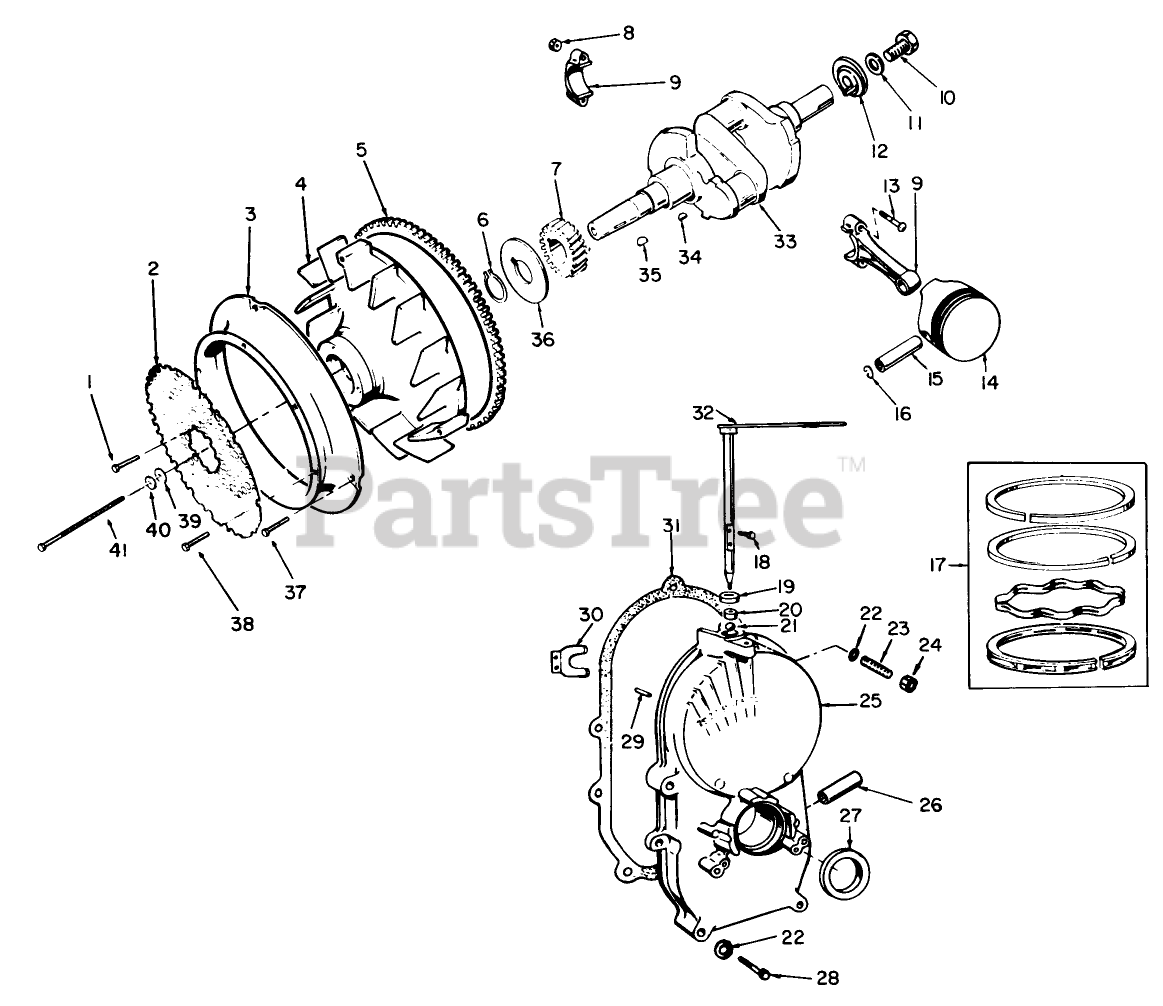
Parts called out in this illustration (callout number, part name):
1	Screw, Cap-Hex Head Locking
2	Guard, Flywheel
3	Venture, Blower Wheel
4	Flywheel (Incl. Ref. #5)
5	Gear, Ring
6	Ring Retaining
7	Gear Crankshaft
8	Nut, Hex-Crown Lock
9	Rod, Connecting-Standard (Incl. Ref. #8 13)
10	Screw, Cap Hex Hd.
11	Washer, Lock-Spring
12	SPACER
13	Bolt, Special-Connecting Rod
14	Piston and Pin-Standard (Incl. Ref. #15 16)
15	Pin, Piston
16	Ring, Retaining
17	Ring Set, Piston-Standard
18	Screw, Machine-Pan Hd.
19	Ball, Bearing-Governor Shaft
20	Bearing, Governor Shaft
21	Seal, Oil-Governor Shaft
22	Washer, Flat Copper
23	Stud, Gear Cover-Top Hole
24	Nut, Gear Cover Top Hole
25	Gear Case Assembly (Incl. Ref. #1 8-21, 23-24, 27-28 30)
26	Tube, Vacuum Port
27	Seal, Oil-Crankshaft
28	Screw Cap Hex Hd.
29	Pin, Dowel-Governor Cup Stop
30	Yoke, Governor Shaft
31	Gasket, Gearcase Mounting
32	Shaft and Arm, Governor
33	STRIP-BULB
34	Key Crankshaft Gear
35	Key Flywheel
36	Washer, Gear Retaining
37	Screw Cap Hex Washer Hd.
38	Screw Tapping Hex Washer Hd.
39	Washer, Flat
40	Washer, Lock-Spring
41	Screw, Cap-Hex Head
